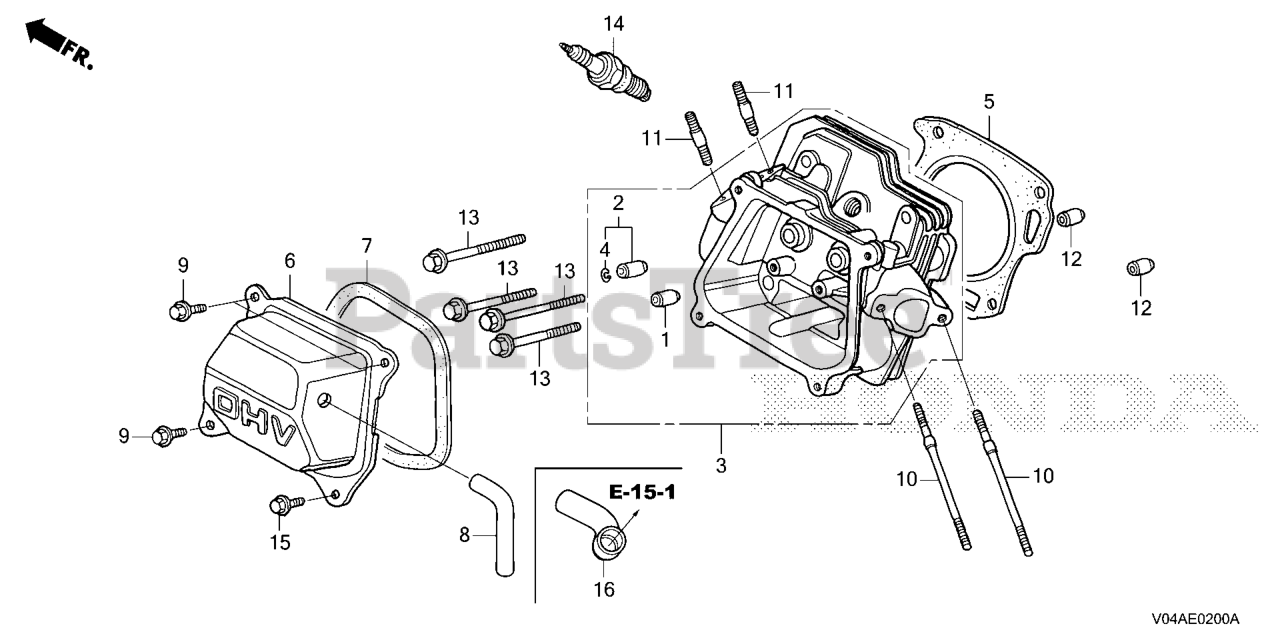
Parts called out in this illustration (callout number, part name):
3	CYLINDER HEAD
4	CLIP, VALVE GUIDE Use from Engine SN 1231803.
5	GASKET, CYLINDER HEAD (NIPPON LEAKLESS)
6	COVER, HEAD
7	GASKET, HEAD COVER
9	BOLT, FLANGE (6X14)
10	BOLT, STUD (6X109)
11	BOLT, STUD (8X32)
12	PIN A, DOWEL (10X16)
13	BOLT, FLANGE (8X60)
14	SPARK PLUG (BPR5ES) (NGK)
14	SPARK PLUG (W16EPR-U) (DENSO)
15	BOLT, FLANGE (6X14)
